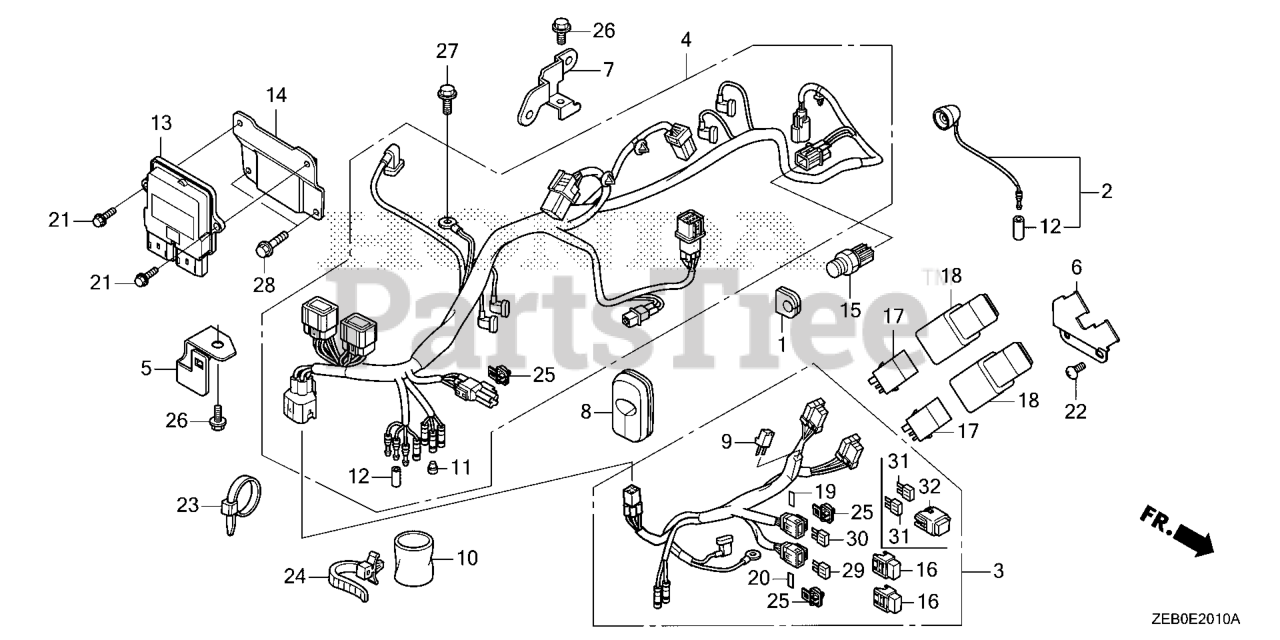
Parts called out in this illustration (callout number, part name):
1	GROMMET, WIRE
2	SUB-WIRE ASSY.
3	SUB-WIRE HARNESS ASSY., ENGINE
4	WIRE HARNESS ASSY., ENGINE
5	BRACKET, HARNESS CLIP
6	BRACKET, RELAY
7	BRACKET B, HARNESS
8	GROMMET, WIRE
9	CONNECTOR, DIODE (2P) (3A)
11	PLUG, CONNECTOR (INNER) (TROLLING CONTROL)
12	PLUG, CONNECTOR (OUTER) (ENGINE NO.)
13	CONTROL UNIT, ELECTRONIC
14	STAY, ELECTRONIC CONTROL UNIT
15	SENSOR ASSY., TEMPERATURE
16	COVER ASSY., FUSE
17	RELAY, POWER (MICRO ISO 4P) (BLUE)
18	SUSPENSION, POWER RELAY
19	LABEL, FUSE (30A)
20	LABEL, FUSE (15A)
21	BOLT, FLANGE (5X14)
22	SCREW, TRUSS (6X12)
23	BAND, WIRE (BLACK)
24	CABLE, STRAP
25	CLIP, CONNECTOR (BLACK)
26	BOLT, FLANGE (6X14)
27	BOLT, FLANGE (6X18)
28	BOLT, FLANGE (6X22)
29	FUSE, MINI (15A)
30	FUSE, MINI (30A)
